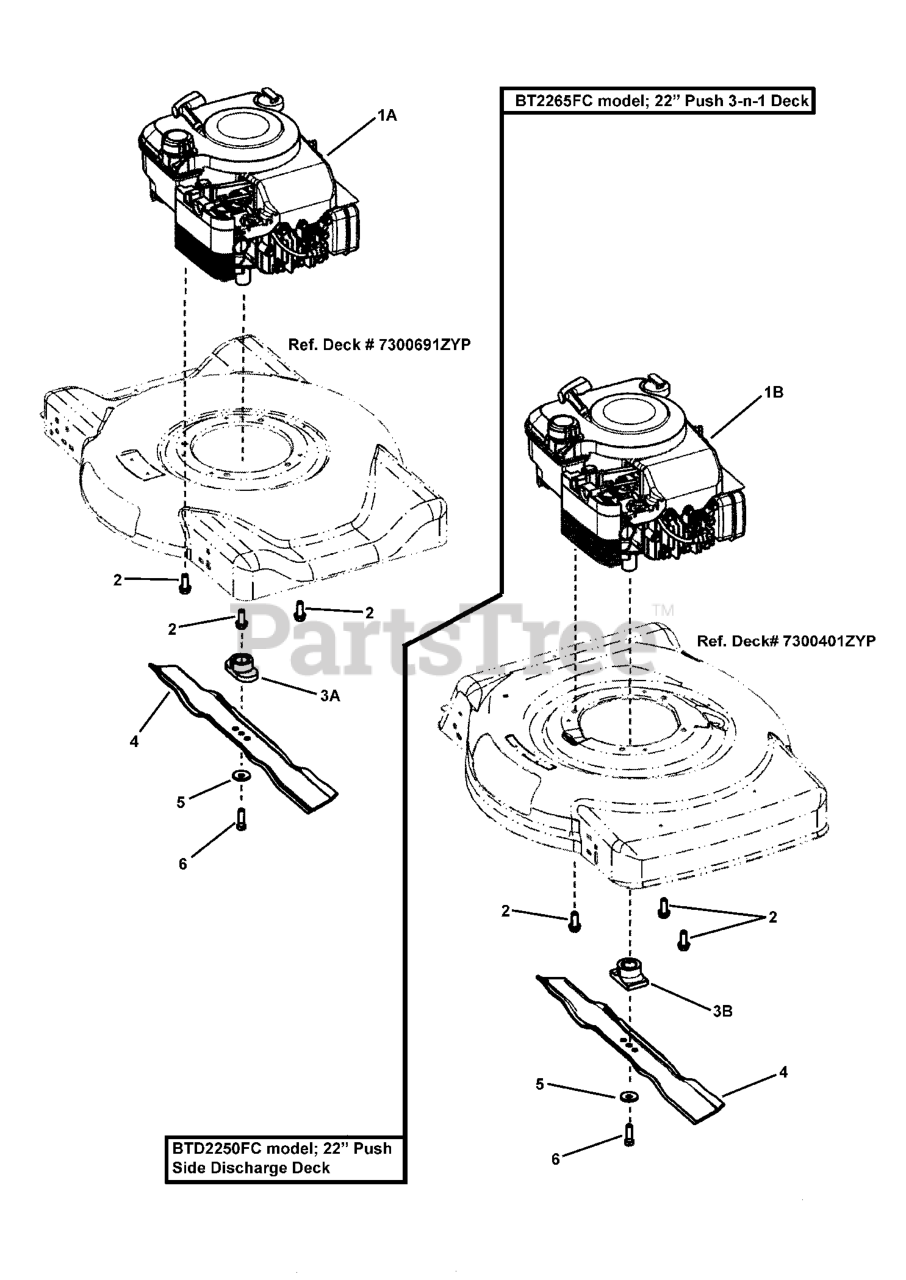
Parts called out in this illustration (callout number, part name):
2	SCREW, 3/8-16 x 1" Hex Washer Self-Tap
3A	HUB, Blade, 22" Push
3B	HUB, Blade, 22" Push
4	BLADE, 22", Walk Mower
5	WASHER, Bellville, .38" ID x 1.183 OD
6	SCREW, 3/8-24 x 1-1/4" Hex Head Cap, GR 5
